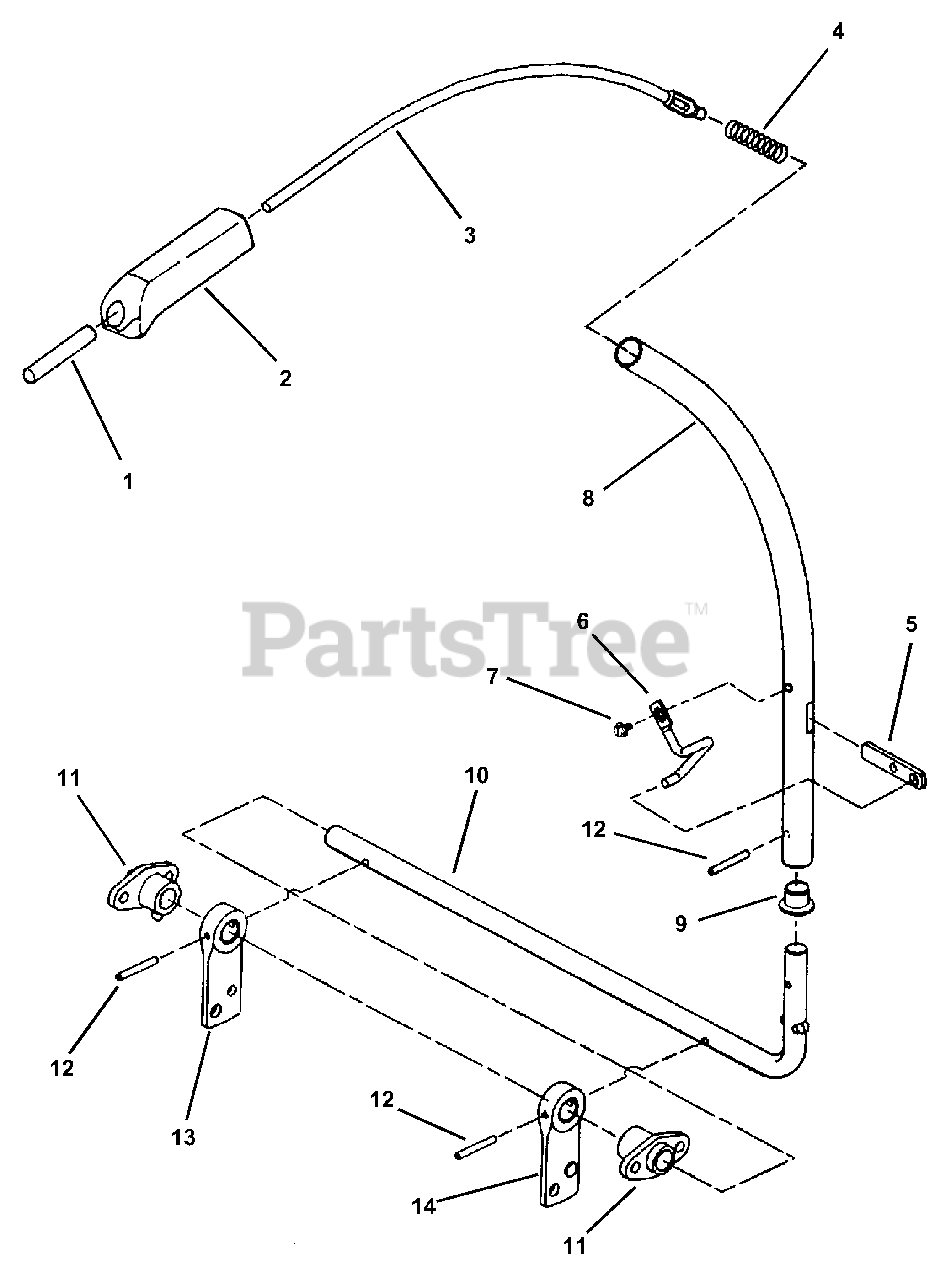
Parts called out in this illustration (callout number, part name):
1	GRIP, 5/16 x 2-1/2" Vinyl
2	GRIP, Brake/Clutch Handle
3	ROD, Park Brake
4	SPRING, Brake/Clutch Release
5	ARM, Brake/Clutch Lever
6	PIVOT, Brake/Clutch Lever
7	SCREW, 1/4-20 x 3/8" Slotted Hex Washer Head, Self-Tapping
8	TUBE, Brake/Clutch Lever
9	BUSHING, Nylon
10	ROD, Brake/Clutch
11	PIVOT, Foot Shaft Assembly
12	ROLL-PIN, 3/16 x 1-1/2"
13	ARM, Brake/Clutch
14	ARM, Brake/Clutch
